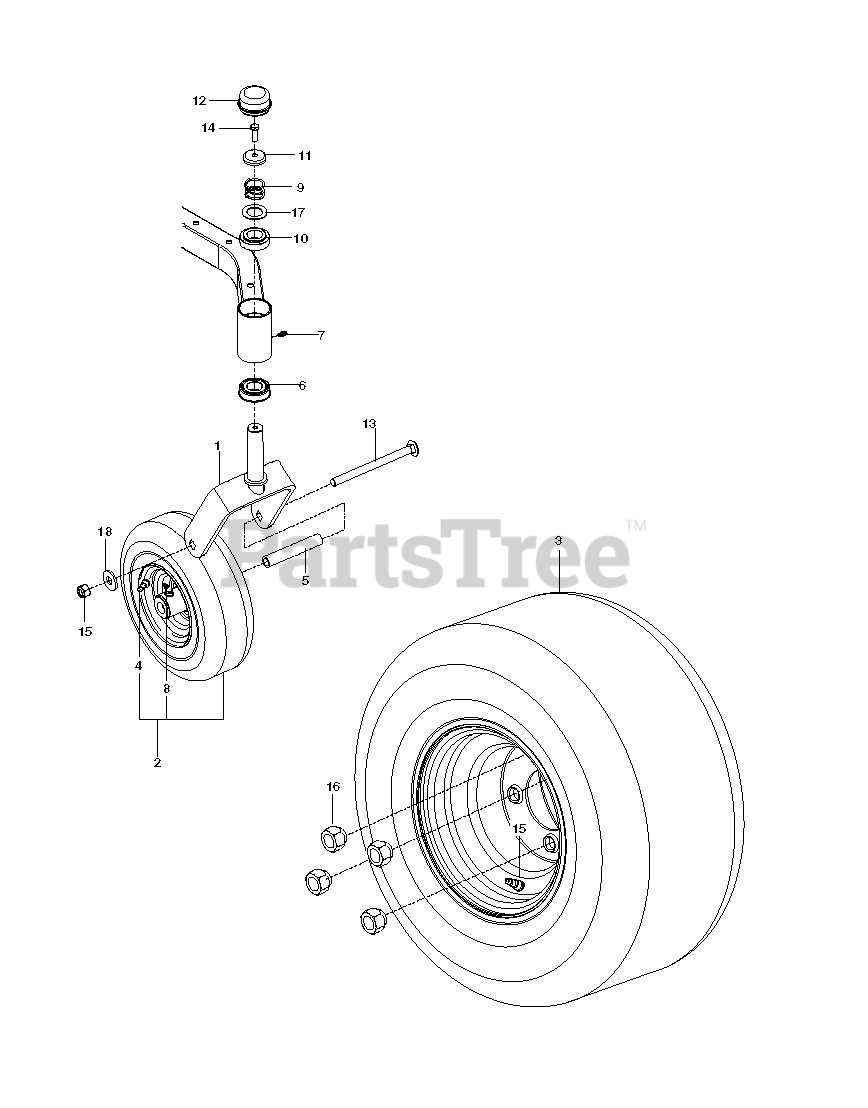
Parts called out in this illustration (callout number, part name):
1	YOKE.CASTER.ORANGE
2	WHEEL ASSY, WIDE, RZ
3	WHEEL.A500.18 X 9.5-8.SILVER
4	VALVE STEM TR-412
5	SPACER, PIVOT
6	BEARING FLANGED
7	ZERK, 3/16, DRIVE IN
8	ZERK
9	SPRING, CASTER
10	BUSHING, CASTER
11	CASTER.PLUG
12	GREASE CAP
13	RHSNB 1/2-13 X 7.5
14	5/16-18X1 HHB G5W/NY
15	NUT 1/2-13 HEX CNTRLK GR 5 ZD
16	LUG NUT 1/2F
17	WASHER, 1.025 ID X 1.64
18	WASH USS FLAT 1/2
